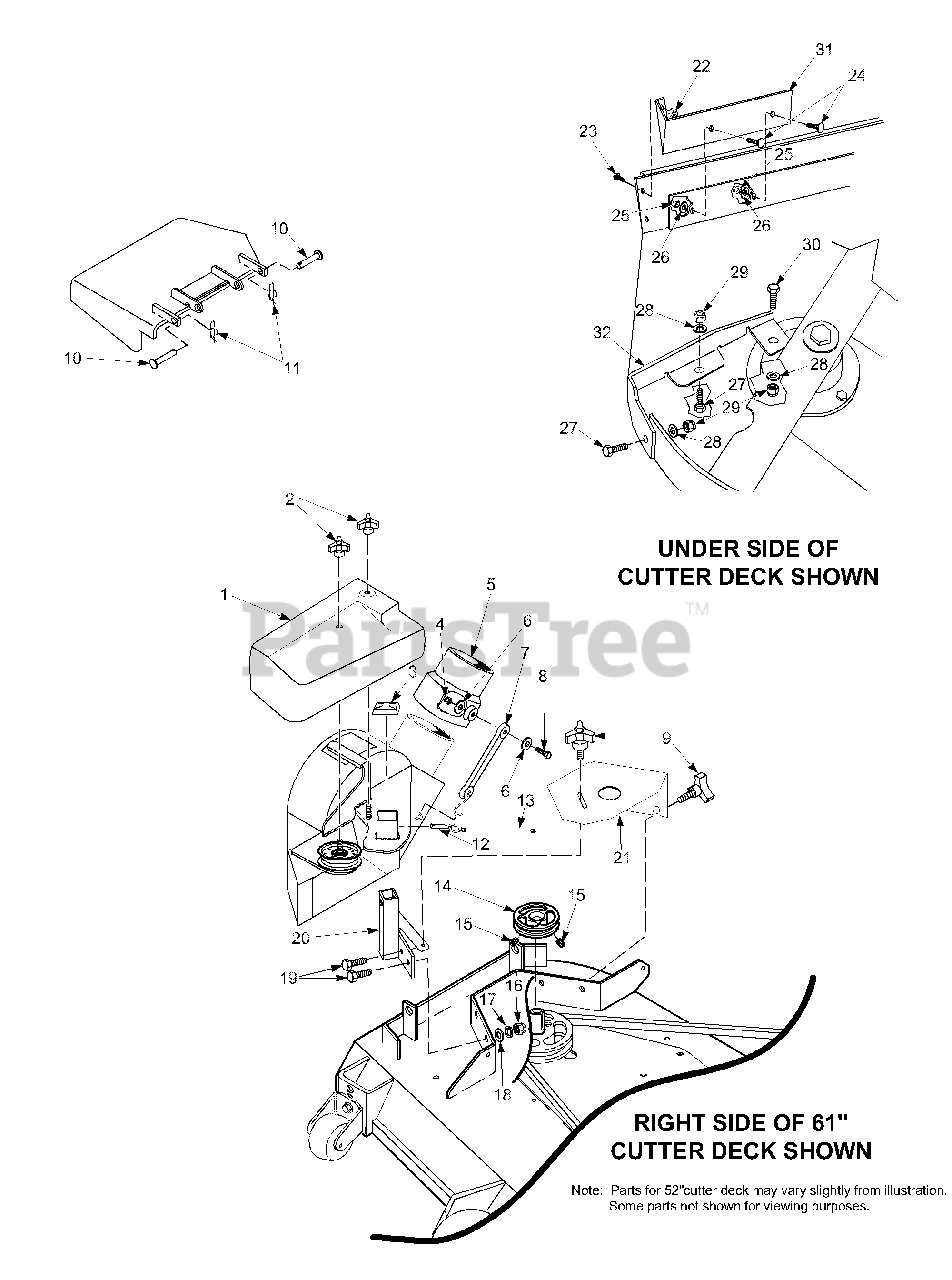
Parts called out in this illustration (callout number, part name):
1	Belt Cover, GC-STT - 52"
2	Wingnut, Plastic 3/8 Small
3	Cap, Square Vinyl
4	Nut, Elastic Stop 1/4-20
5	Adapter, Blower GC-STT
6	Flatwasher, 1/4-.312 x .750 x .065
7	Rubber Strap 7-3/4"
8	Bolt, Hex Head 1/4-20 x 1-1/4"
9	Knob W/Stud, 3/8-16 x 1-1/4"
10	Clevis Pin, 5/16 x 1-1/2"
11	Pin, Rue Cotter 5/16 Dia.
12	Pin, Ring 1/2 x 2-1/4"
13	Lanyard
14	Pulley, 4-1/2" for 52" Deck
15	Setscrew, 5/16-18 x 3/8"
16	Nut, Elastic Stop 1/2-13
17	Lockwasher, 1/2"
18	Flatwasher, 1/2-.531 x 1.062 x .095
19	Bolt, Hex Head 1/2-13 x 1-1/2" Grade 5
20	Mounting Post Weldment, Blower - 52"
21	Belt Cover, - 52"
22	Nut, Serrated Flange 1/4-20
23	Bolt, Hex Head 1/4-20 x 3/4"
24	Bolt, Carriage 3/8-16 x 1"
25	Nut, Elastic Stop 3/8-16
26	Flatwasher, 3/8-.391 x .938 x .105
27	Bolt, Hex Head 5/16-18 x 1"
28	Flatwasher, 5/16-.375 x .875 x .083
29	Nut, Elastic Stop 5/16-18
30	Bolt, Hex Head 5/16-18 x 1-3/4"
31	Baffle, 52"
32	Baffle, 52" Deck
